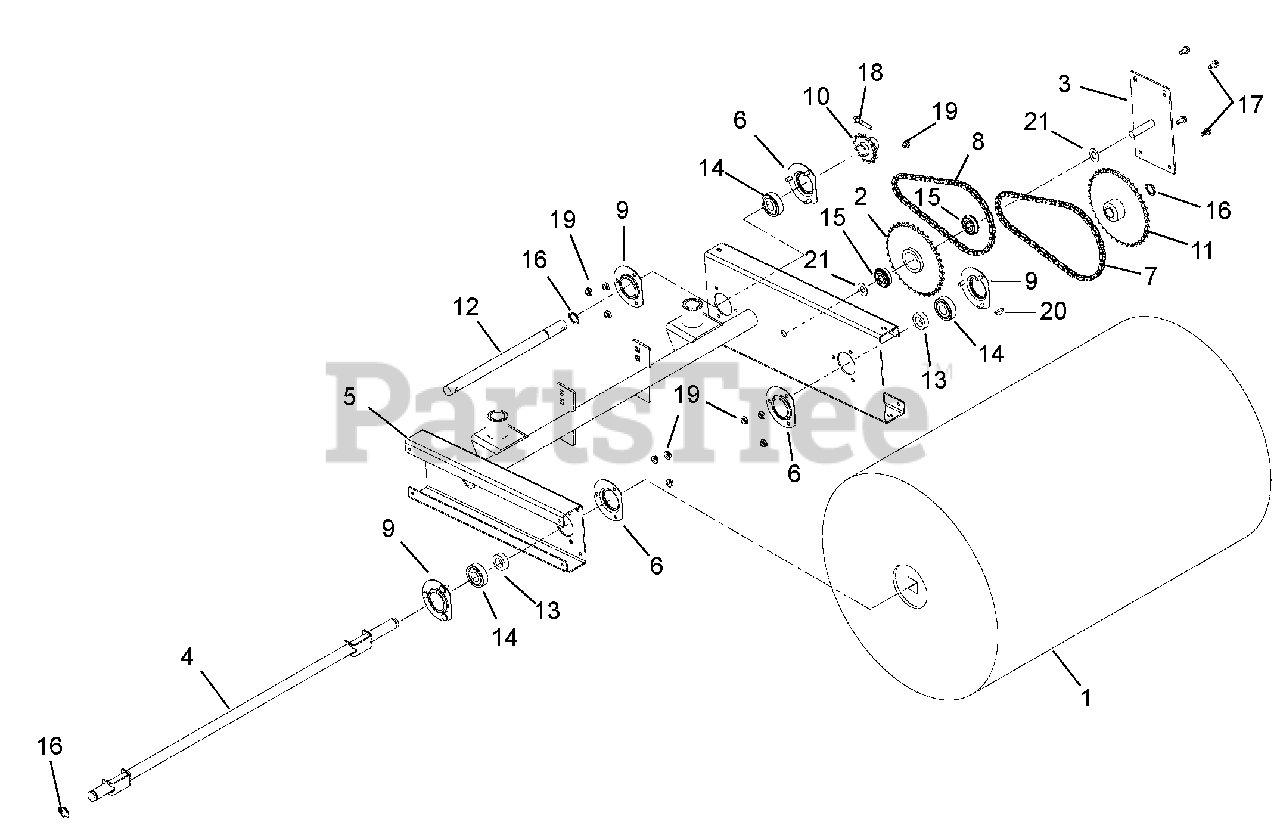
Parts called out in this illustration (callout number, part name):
1	Brush, 18" Diameter x 28" Wide
2	Sprocket, Reduction Idler
3	Mount, Reduction Idler
4	Shaft, 28" Brush
5	Frame, 28" Brush
6	Bearing, Flange
7	Chain, #40 – 54 Links
8	Chain, #41 – 50 Links
9	Bearing, Flange
10	Sprocket, Drive
11	Sprocket, Driven
12	Shaft, Transmission
13	Spacer, .755 x 1.250 x .370
14	Bearing, Ball .750 x 1.750 x .50
15	Bearing, Ball .50 x 1.38 x .438 Sealed
16	Ring, Retaining, External .689 x .077
17	Screw, Tapping .25-20 x .50 Hex Washer Head Thread Rolling
18	Bolt, Hex .25-20 x 1.75 Grade 5
19	Nut, Locking-Top-Flange .25-20
20	Key, Woodruff .188 x .75 x .313 SAE 9
21	Washer, Flat Steel .563 x 1.38 x .109
